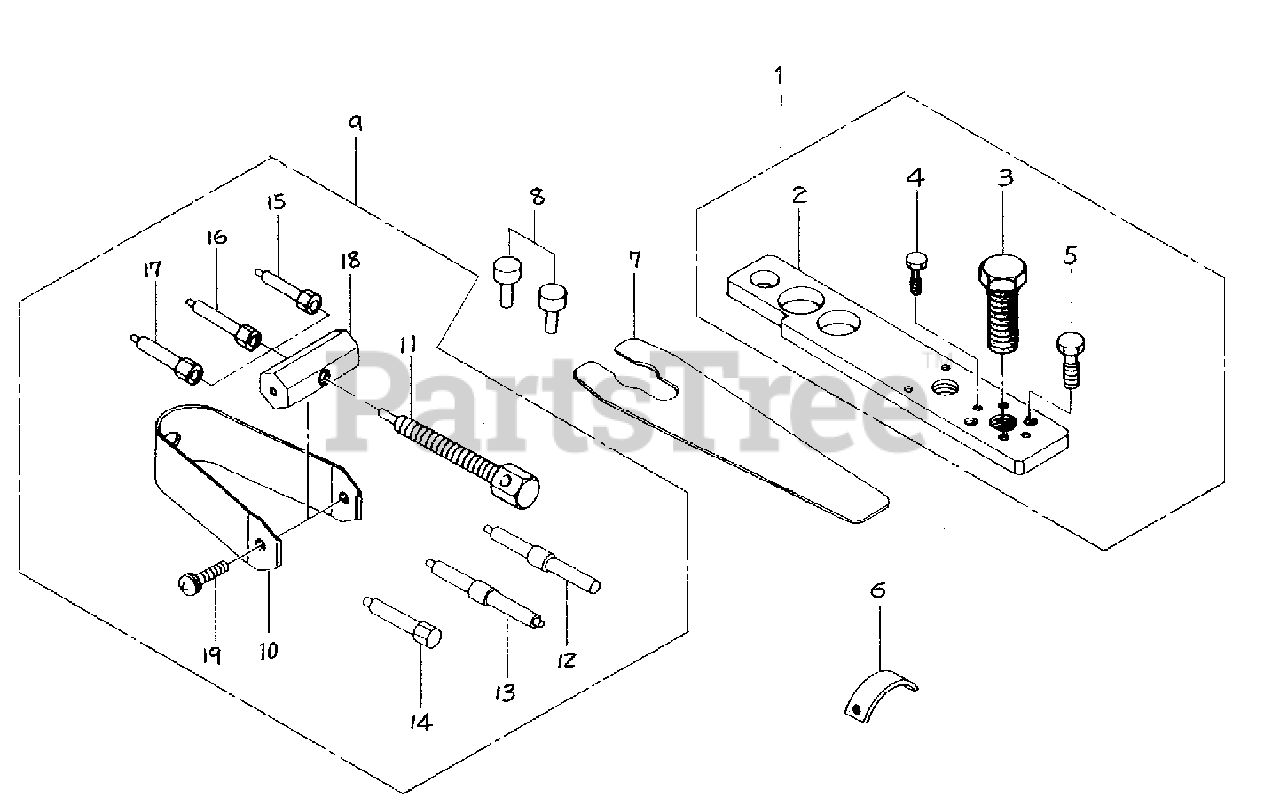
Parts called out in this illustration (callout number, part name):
1	STARTER PAWL ASSY
2	LEVER
3	BOLT, CENTER
4	BOLT
5	BOLT
6	AIR GAP GAUGE
7	SPANNER, ROTOR
8	STOPPER
9	STARTER PAWL ASSY SERVICE TOOL
11	BOLT
12	GUIDE PIN
13	GUIDE PIN
14	GUIDE PIN
15	PIN - ADAPTOR
16	PIN - ADAPTOR
17	PIN - ADAPTOR
18	BOSS
19	SCREW - 6X12
